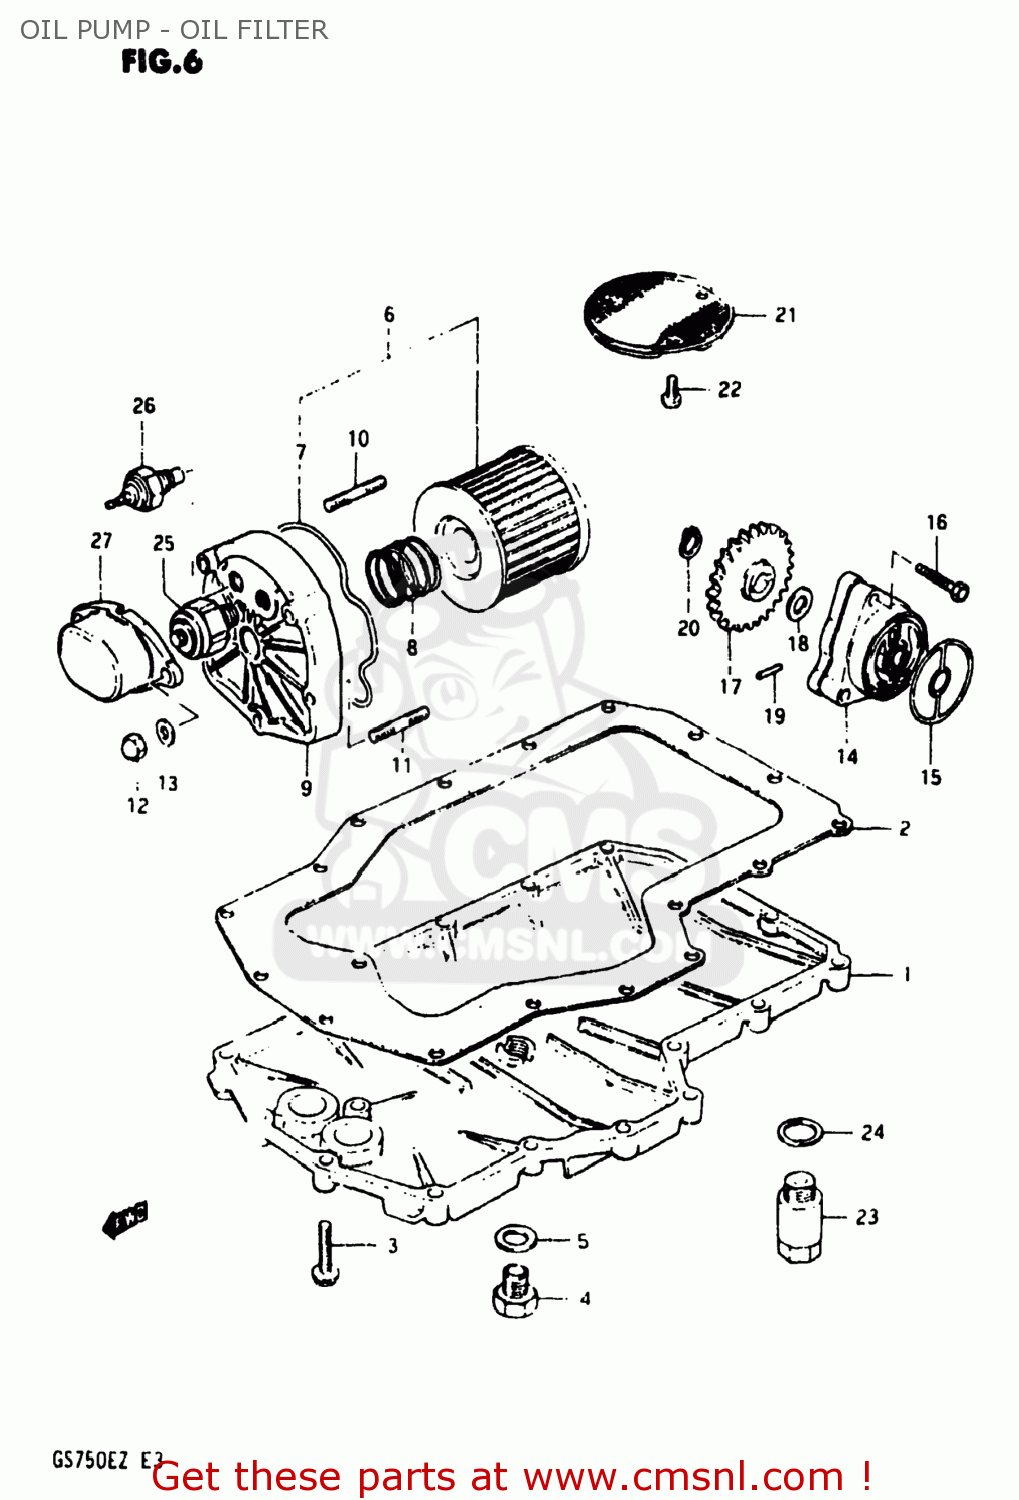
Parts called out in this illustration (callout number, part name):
1	PAN,OIL
2	GASKET,OIL PAN (MCA)
3	BOLT
4	PLUG
5	GASKET(14X19.2X2) (NAS)
6	FILTER ASSY,ENGINE OIL
7	O RING,OIL FILTER CHAMBER CAP
8	SPRING
9	CAP,ENGINE OIL FILTER
10	STUD 6X30
11	STUD 6X25
12	NUT
13	WASHER
14	PUMP ASSY,ENGINE OIL
15	O-RING,OIL PUMP
16	BOLT(6X32)
17	GEAR,ENG OIL PUMP DRIVEN
18	SHIM
19	PIN(4X15.8)
20	CIRCLIP
21	STRAINER,ENGINE OIL
22	SCREW 6X12
23	VALVE ASSEMBLY,OIL RELIEF
24	WASHER
25	SWITCH ASSEMBLY
26	GAUGE ASSEMBLY,OIL TEMPERATURE
27	COVER,OIL PRESSURE SWITCH
